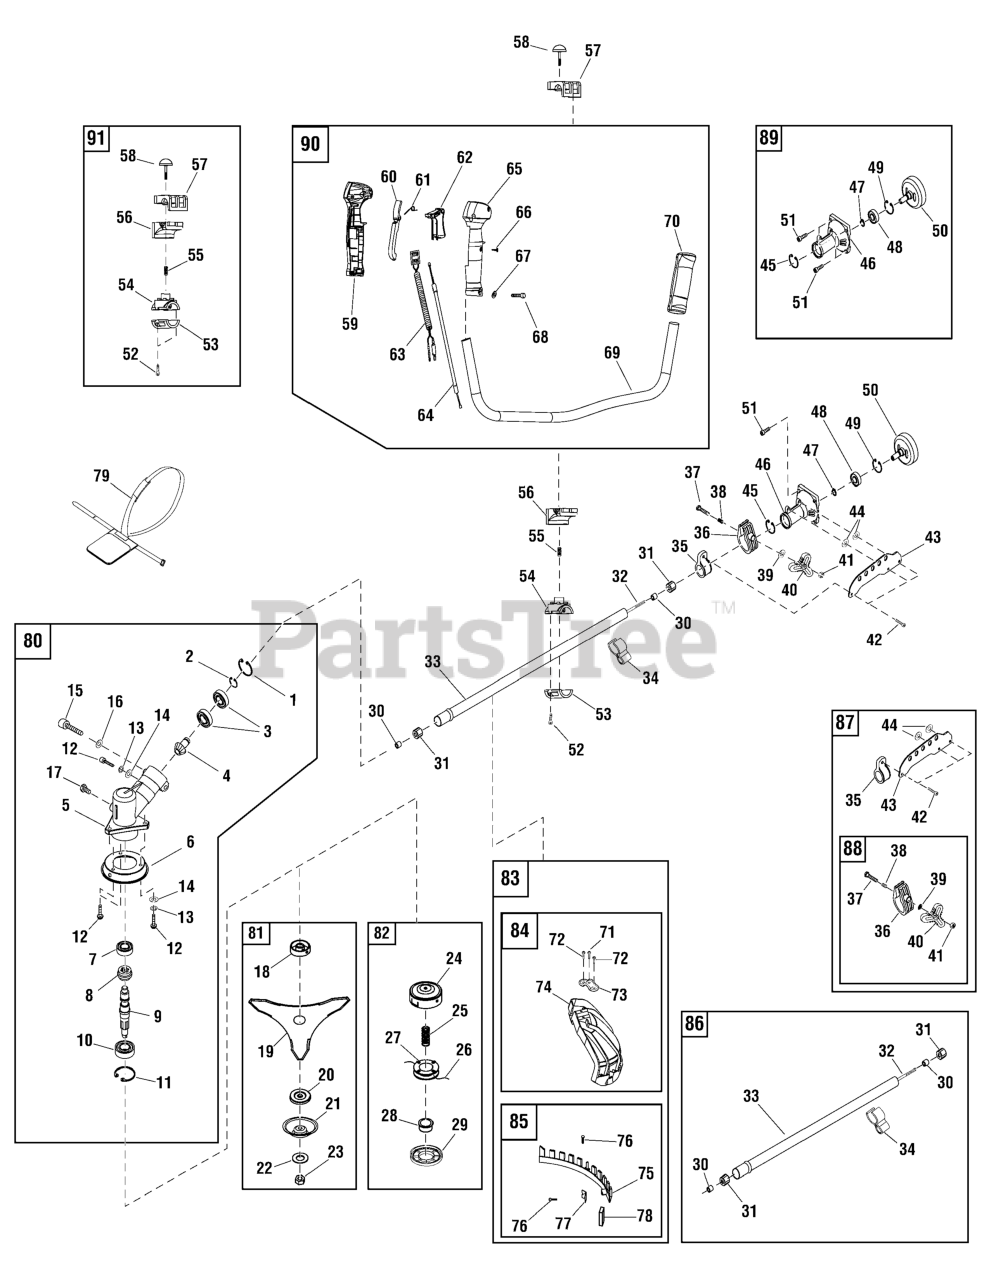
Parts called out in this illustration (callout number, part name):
4	PINION
5	GEAR BOX
6	COVER, Blade
8	GEAR
9	SHAFT, Spline
12	BOLT, M5 x 12
13	WASHER, Spring, 5
14	WASHER, Flat, 5
15	* BOLT, M6 x 20
16	WASHER, Spring, 6
18	GASKET, Spline
20	HOLDER
21	PROTECTOR, Blade
22	WASHER, Wave, Dia 10
24	BOX, Bump Head
25	SPRING, Bump Head
26	ROPE, Bump Head
27	ROPE BOX
28	BUMP HEAD
29	COVER, Bump Head
30	BEARING, Oil
31	RUBBER COVER, Bearing Oil
32	DRIVE SHAFT
33	SHAFT, Straight
34	RETAINER, Wire
35	RING, Hang
36	RING FOR LIMIT
37	* BOLT, Hex Head
38	SPRING
40	HANDLE, Self Lock
41	* NUT, Hex Head
43	HANG HANDLE
44	SPACER, Hang Handle
46	CASE, Clutch
50	CLUTCH DRUM, Complete
53	BRACKET, Shaft, Lower
54	BRACKET, Shaft, Upper
55	SPRING
56	BRACKET, Handle, Lower
57	BRACKET, Handle, Upper
58	BOLT, With Knob, Red
59	COVER, Handle, Control Switch, LH
60	HANDLE, Self Lock
61	SPRING, Torsion
62	LEVEL, Throttle
63	STOP BUTTON, Complete
64	CABLE, Comp.
65	COVER, Handle, Control Switch, RH
66	SCREW, Self Tapping, M3.5 x 13
67	WASHER, Flat, Dia 5
68	SCREW, M5 x 30
69	HANDLE
70	COVER, Handle
71	* BOLT, M5 x 10
72	* BOLT, M5 x 12
73	HOLDER, Saftey Guard
74	SAFETY GUARD
75	SECURING SADDLE
76	SCREW, Self Tapping, ST4.2 x 16
78	COVER, Blade
80	KIT, Gear Box Assembly
81	KIT, Blade Assembly
82	KIT, Bump Head Assembly
83	KIT, Guard Assembly
84	KIT, Blade Guard
85	KIT, Securing Saddle Assembly
86	KIT, Drive Shaft Assembly
87	KIT, Hang Handle Assembly
88	KIT, Limit Ring Assembly
89	KIT, Clutch Assembly
90	KIT, Handle Assembly
91	KIT, Handle Bracket Assembly
